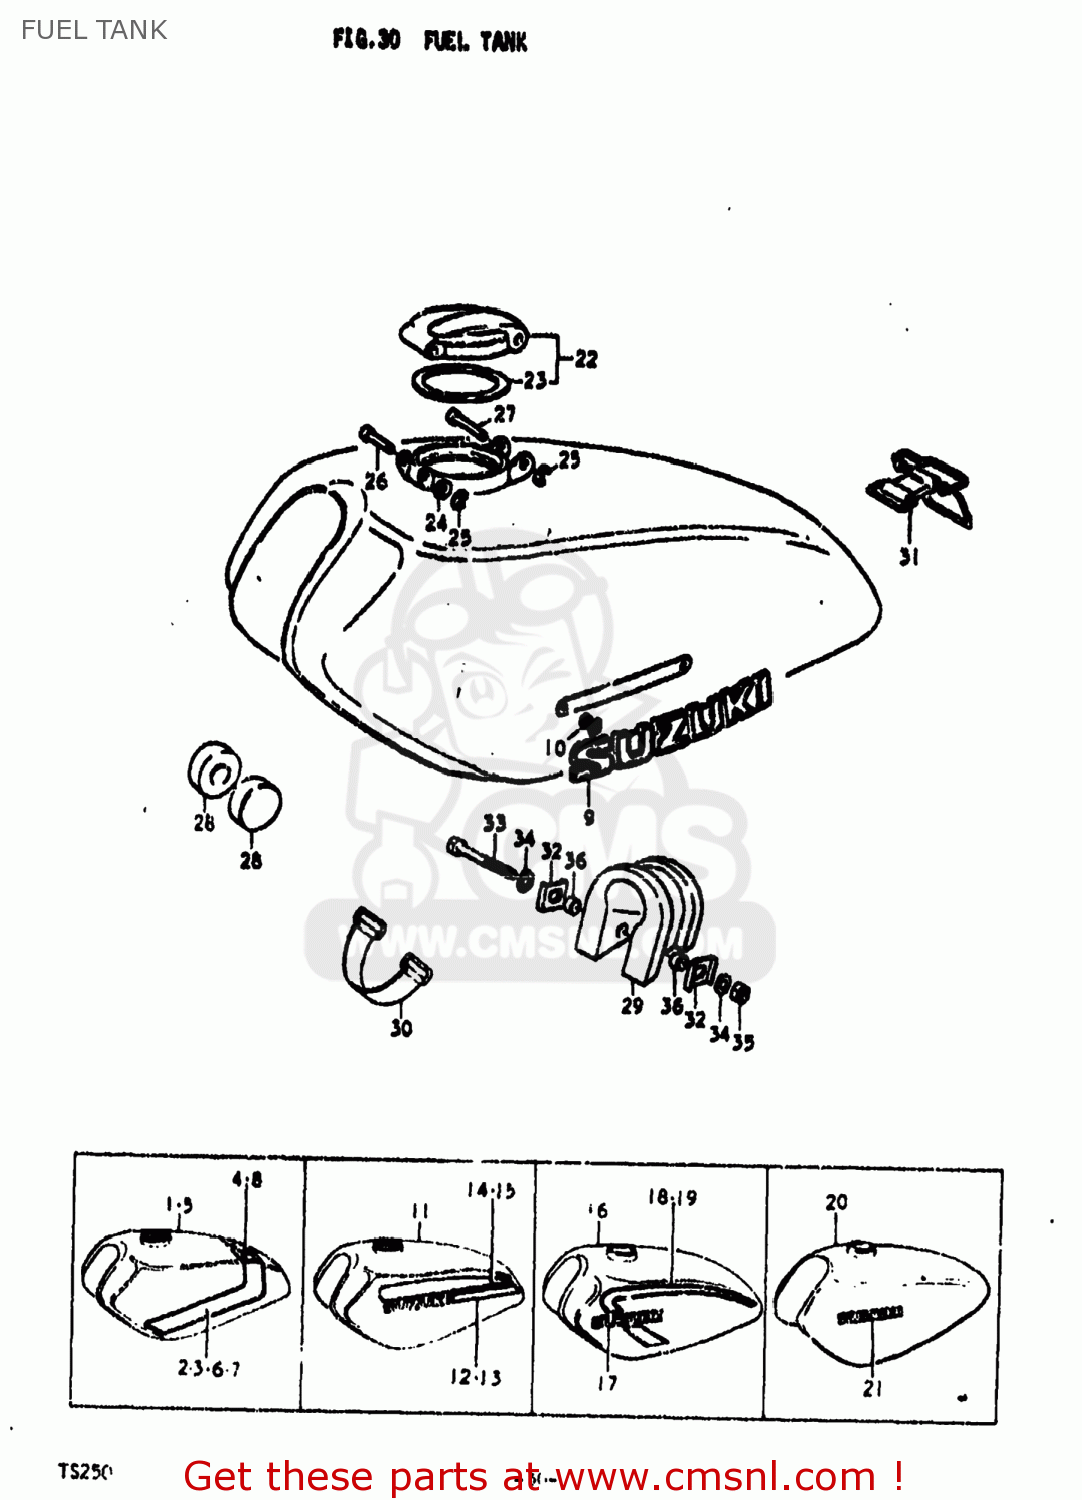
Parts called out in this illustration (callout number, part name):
1	TANK ASSEMBLY,FUEL
2	TAPE,FUEL TANK
3	TAPE,FUEL TANK
5	TANK ASSEMBLY,FUEL
6	TAPE,FUEL TANK
7	TAPE,FUEL TANK
9	EMBLEM
10	NUT
11	TANK ASSEMBLY,FUEL
12	EMBLEM
13	EMBLEM,FUEL TANK
14	TAPE,FUEL TANK
15	TAPE,FUEL TANK
16	TANK ASSEMBLY,FUEL
17	EMBLEM
18	TAPE,FUEL TANK
19	TAPE,FUEL TANK
20	TANK ASSEMBLY,FUEL
21	EMBLEM,FUEL TANK
22	CAP ASSEMBLY,FUEL TANK
23	GASKET (NAS)
24	WASHER
25	E RING
27	PIN,FUEL TANK C
28	CUSHION
29	CUSHION,FUEL TANK,REAR
30	BAND
31	BAND
32	CLIP
33	BOLT
34	WASHER 6MM
35	NUT
36	SPACER (6.1X8X5.2)
